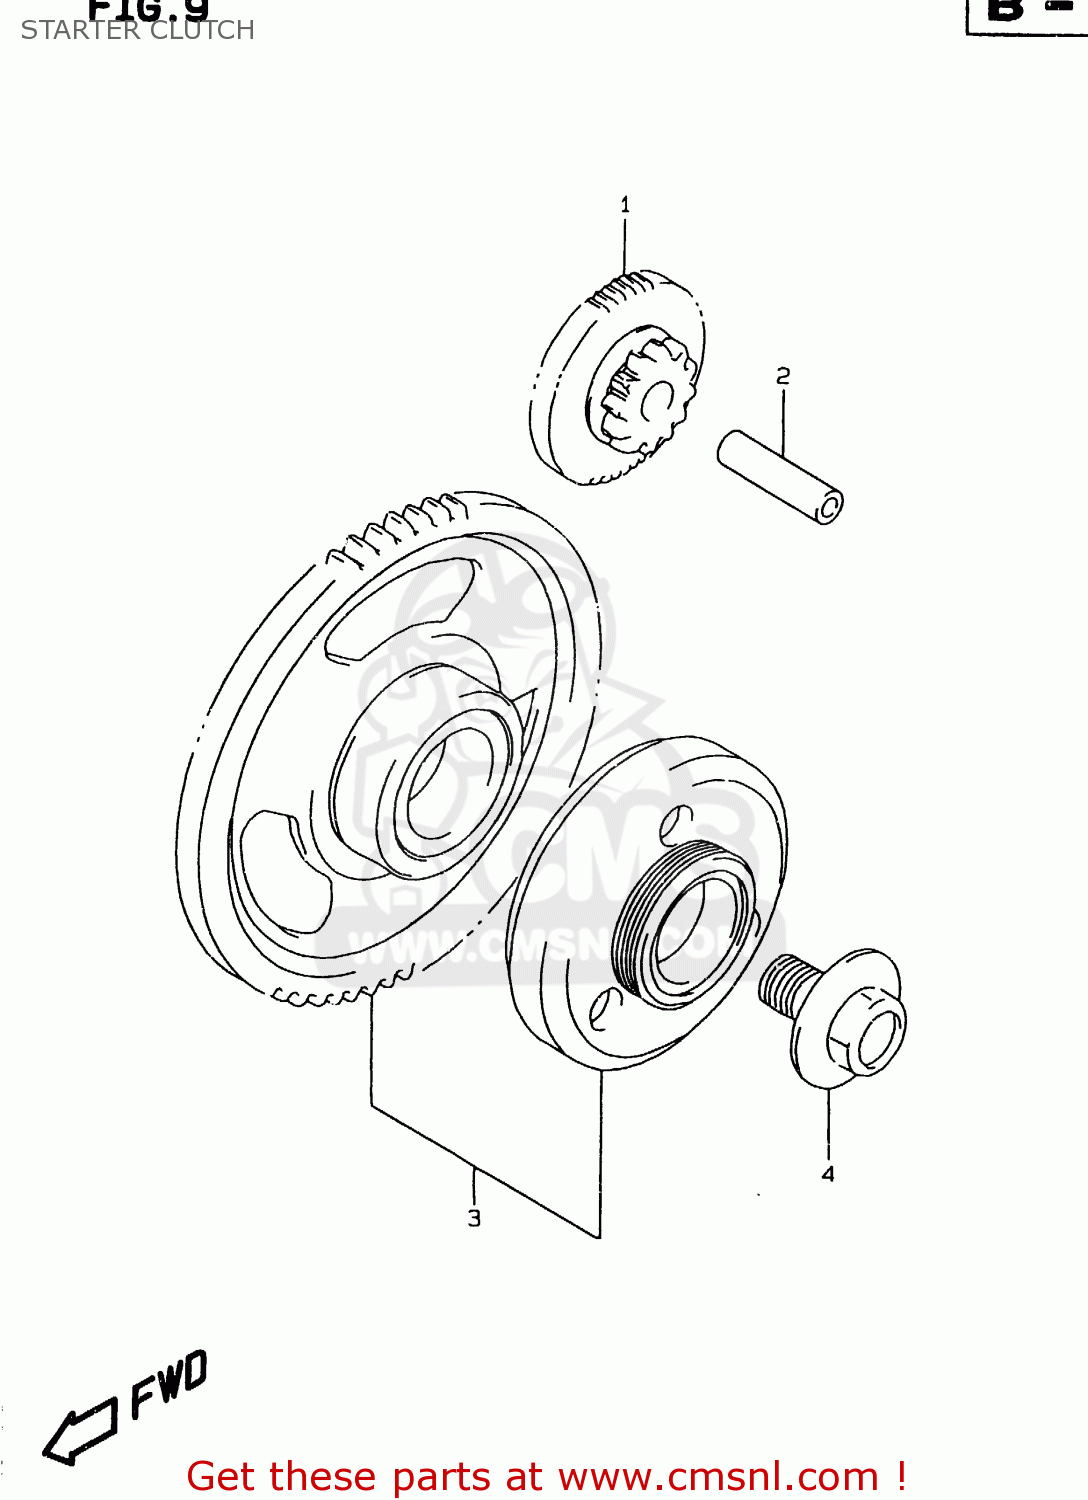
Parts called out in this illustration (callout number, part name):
1	GEAR,STARTER IDLE(NT:12,53)
2	PIN(7X11X42)
3	CLUTCH SET,STARTER
4	BOLT(14X21)
